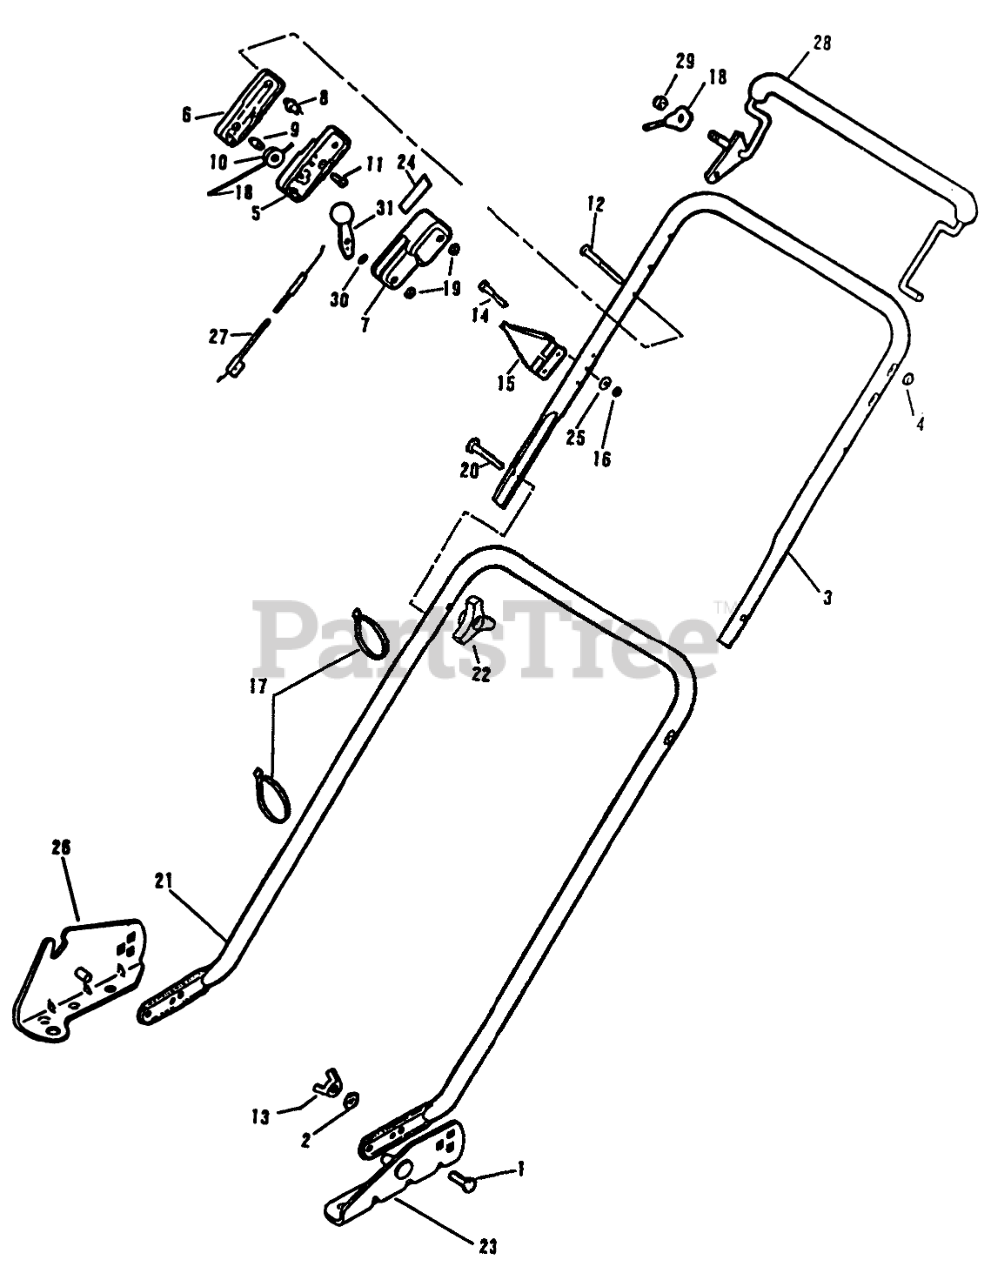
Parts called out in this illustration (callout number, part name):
1	Bolt
2	WASHER LOCK B'GER
3	Handle-Top
4	NUT-PUSH
5	CENTER CONTROL CASE
6	OUTER CONTROL CASE
7	INNER CONTROL CASE
8	COLUMN
9	PIN SKF
10	PULLEY PL
11	SCREW
12	SCREW
13	NUT WING
14	SCREW
15	GUIDE - ROPE
16	LOCKNUT E
17	TIE-CABLE
18	CONTROL CABLE
19	NUT C/LOCK E
20	Screw
21	HDLE-LOWER(GREEN
22	Knob
23	HANDLE BRKT & PIN
24	DECAL-THROT CONTRL
25	WASHER
26	Bracket-Handle-R.H.
27	CABLE TH'TTLE WES
28	CONTROL LEVER ARG
29	NUT ACORN
30	WASHER-SPRING
31	LEVER&KNOB AY WES
